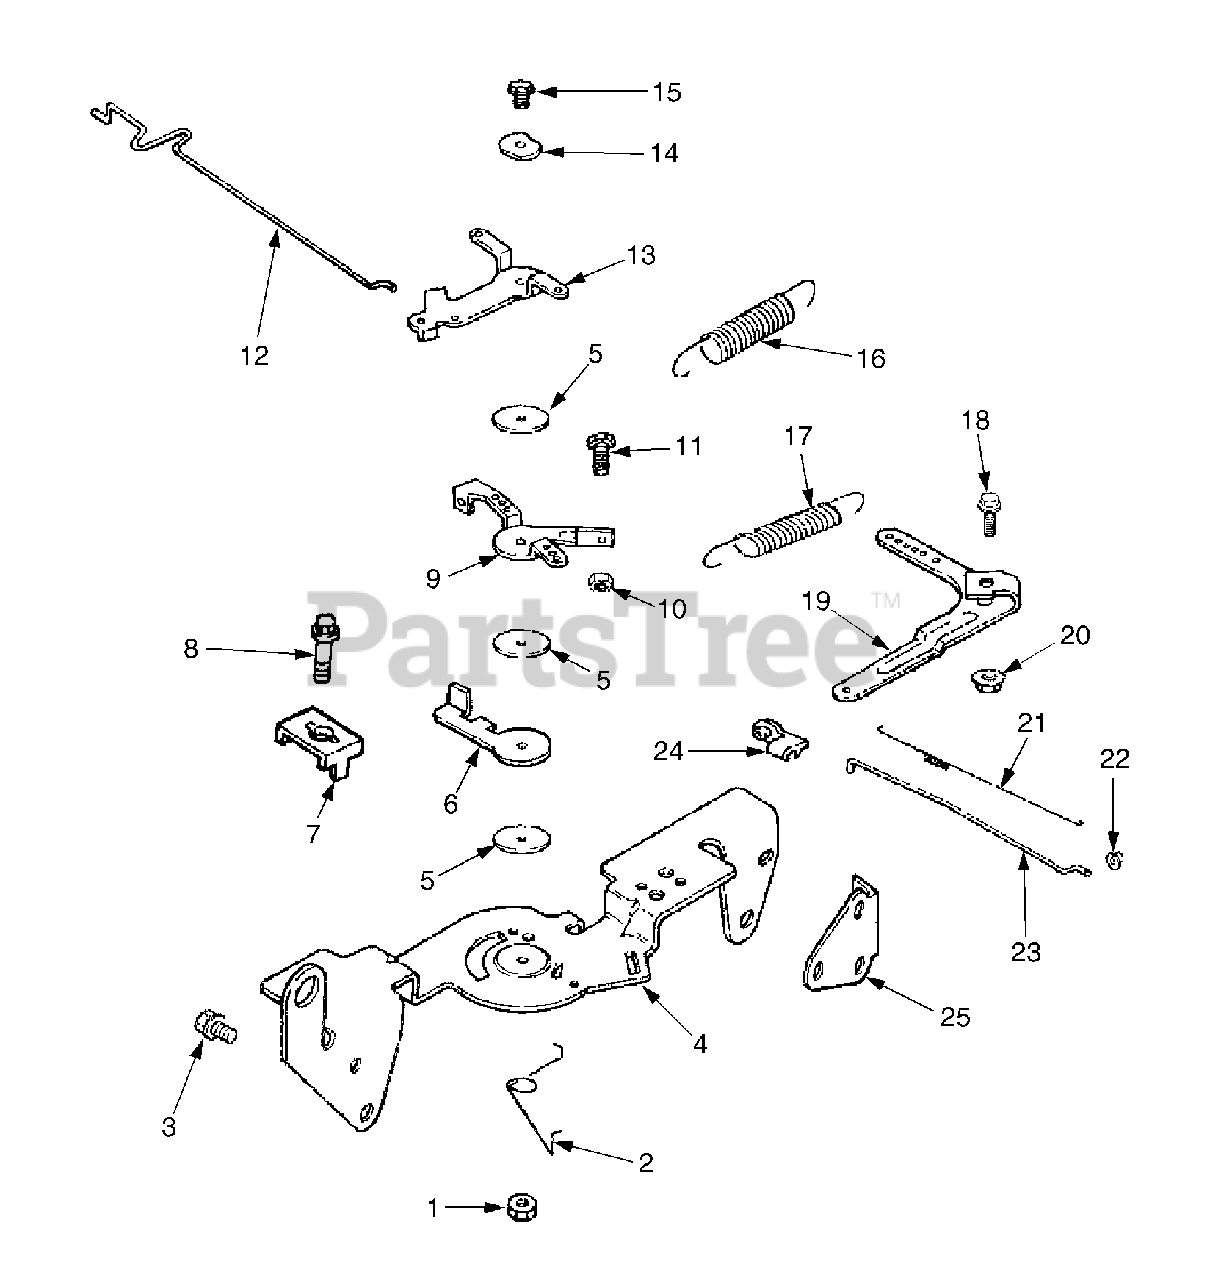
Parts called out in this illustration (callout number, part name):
1	Nut, Hex Lock M5 x 0.8
2	Spring, Choke Return
3	Screw, Hex Flange M6 x 1.0 x 16
4	Bracket, Control
5	Washer, Plain 5.5 mm
6	Lever, Throttle Actuator
7	Clamp,Cable,
8	Screw, Hex Flange M5 x 0.8 x 16
9	Lever, Throttle Control
10	Nut, Hex M4 x 0.7
11	Screw, Hex Cap M4 x 0.7 x 30
12	Linkage, Choke
13	Lever, Choke
14	Washer, Spring 1/4"
15	Screw, Hex Flange M5 x 0.8 x 20
16	Spring, Throttle Limiter
17	Spring, Gov., (6mm Gov. Shaft)
18	Screw, Hex Flange (6mm)
19	Lever, Governor (6mm)
20	Nut, Hex Flange M6 x 1.0"
21	Spring, Linkage
22	Bushing, Linkage Retaining
23	Linkage, Throttle
24	Bushing, Linkage Retaining
25	Bracket Support
